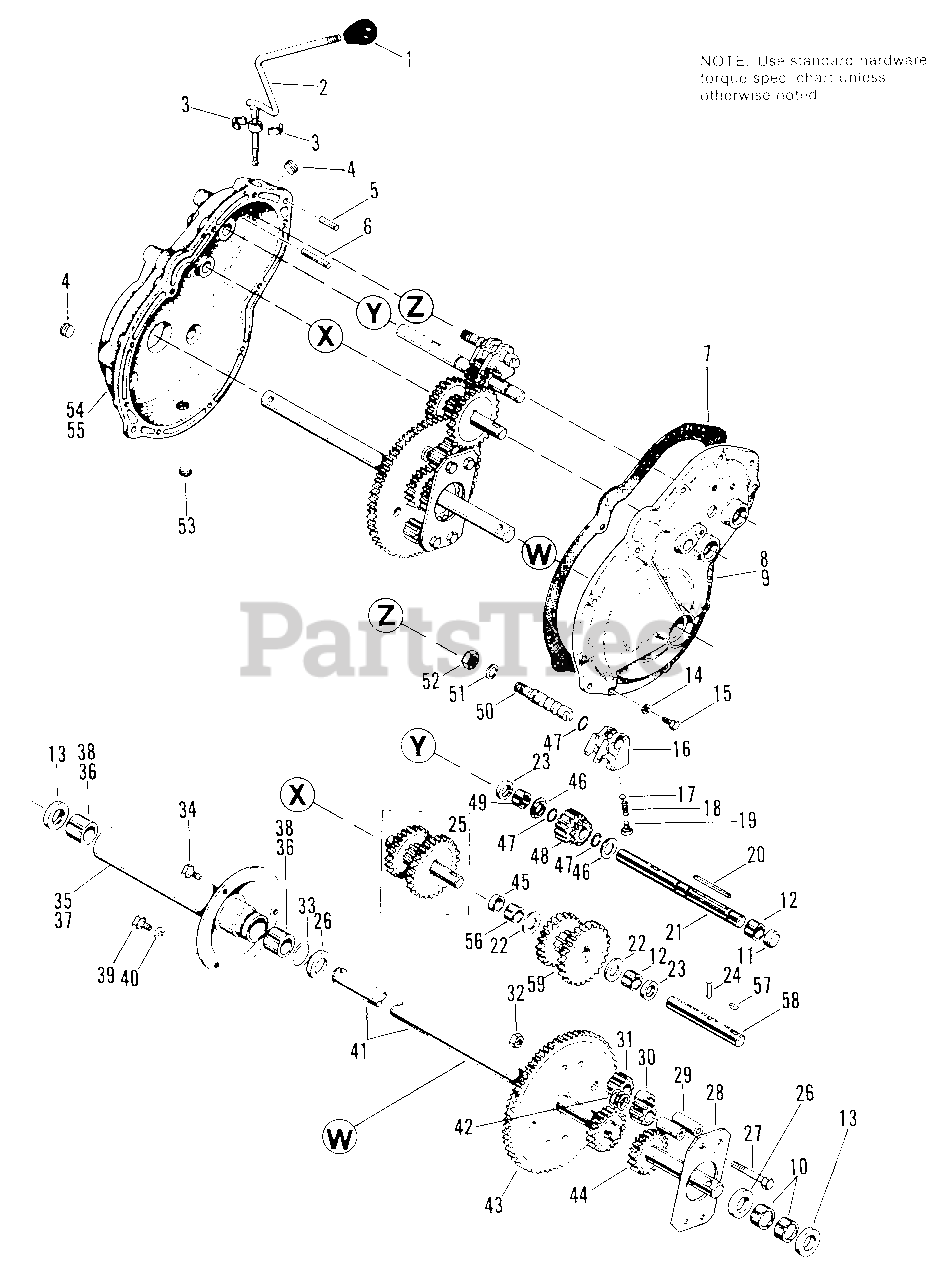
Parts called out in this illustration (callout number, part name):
1	KNOB
2	ROD ASSY., Shift
3	BUSHING, Ball, Half
5	PIN, Roll, 3/8 Dia. x 1
6	PIN, Roll, 5/16 Dia. x 3
8	COVER ASSY., Gear Case
9	COVER, Gear Case
11	PLUG, Expansion
14	LOCKWASHER, 5/16
15	CAPSCREW, Hex Hd., 5/16-18 x 1-1/4
16	FORK, Shift, Hi-Lo
19	CAPSCREW, Hex Hd., 5/16-18 x 5/16
21	SHAFT, Pulley
24	PIN, Dowel
25	SHAFT & GEAR ASSY.
27	CAPSCREW, Hex Hd., 3/8-16 x 2-1/2
28	PLATE, Diff.
32	LOCKNUT, Hex, 3/8-16
34	CAPSCREW, Special
35	HOUSING ASSY., Axle
37	HOUSING ASSY., Axle
39	CAPSCREW, Hex Hd., 3/8-16 x 7/8
40	LOCKWASHER, 3/8
41	AXLE ASSY., L.H.
43	GEAR ASSY., Drive
44	AXLE ASSY., R.H.
45	PLUG, Expansion
47	RING, Retaining
48	PINION ASSY., Hi-Lo
50	SHAFT, Shift, Reverse, Lo
51	LOCKWASHER, 7/16
52	NUT, Hex, Full, 7/16-14
53	PLUG, Pipe
54	GEAR CASE ASSY.
55	CASE, Gear
57	KEY, Woodruff, 5/32 x 5/8
58	SHAFT, Brake
59	CLUSTER ASSY., Gear
